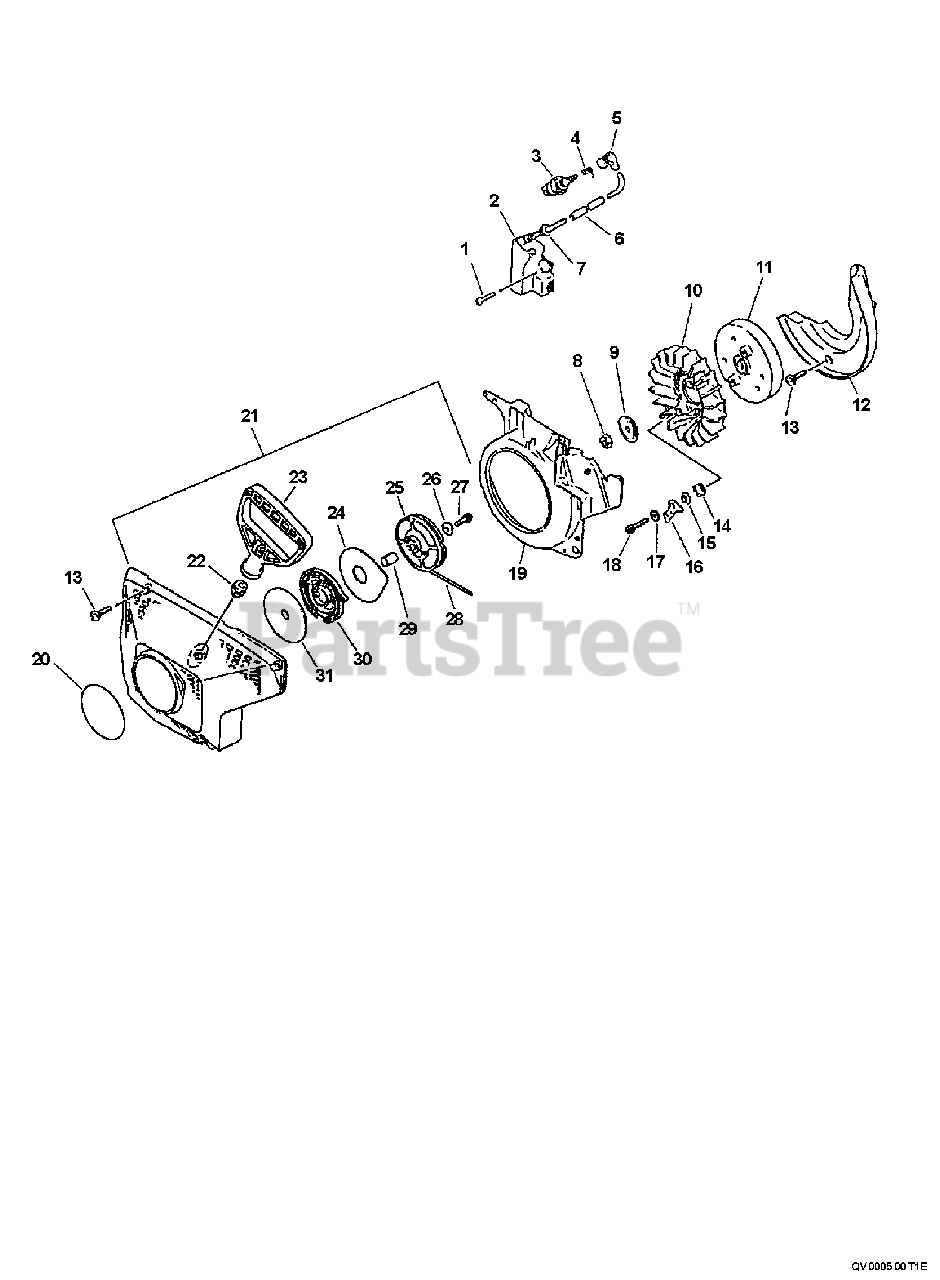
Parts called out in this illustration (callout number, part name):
1	SCREW - 4X20
2	COIL, IGNITION
3	SPARK PLUG -- CJ-6Y
4	TERMINAL, SPARK PLUG CAP
5	CAP, SPARK PLUG
8	NUT - FLANGE
9	WASHER - CUP
11	FLYWHEEL
12	SHIELD, FAN
13	SCREW - 5X20
14	SPRING, RETURN
16	PAWL, STARTER
17	WASHER - 5
18	SCREW - 5X30
19	SHIELD, FAN
20	LABEL - ECHO
21	STARTER ASSY
22	GUIDE, ROPE
23	GRIP, STARTER
24	PLATE, STARTER
25	REEL, ROPE
26	WASHER - 5
27	SCREW - 5X14
28	ROPE, STARTER - 4X950
30	SPRING, REWIND
31	PLATE, STARTER
